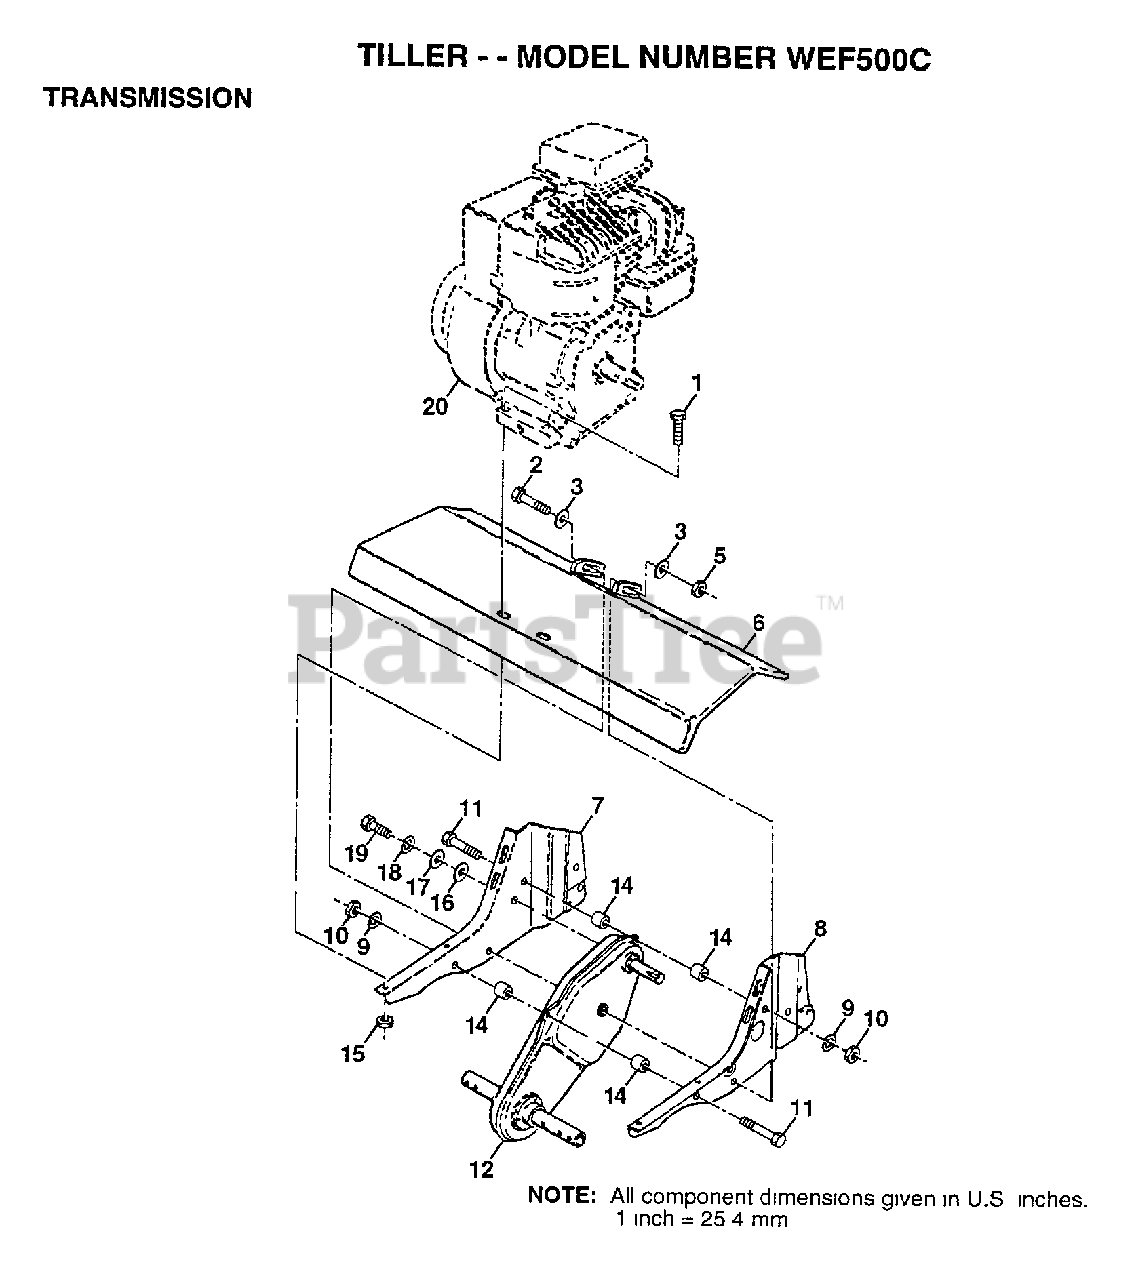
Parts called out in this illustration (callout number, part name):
1	BOLT.HEX.5/16-1.5
2	BOLT HEX 3/8-16
3	WASHER
5	NUT
6	SHIELD.PNT.TINE
8	BRACKET.ENG.LH.
9	LOCKWASHER
10	NUT.HEX.5/16-18
14	SPLIT SPACER RT
16	WASHER
17	WASHER
18	LOCKWASHER
19	BOLT
